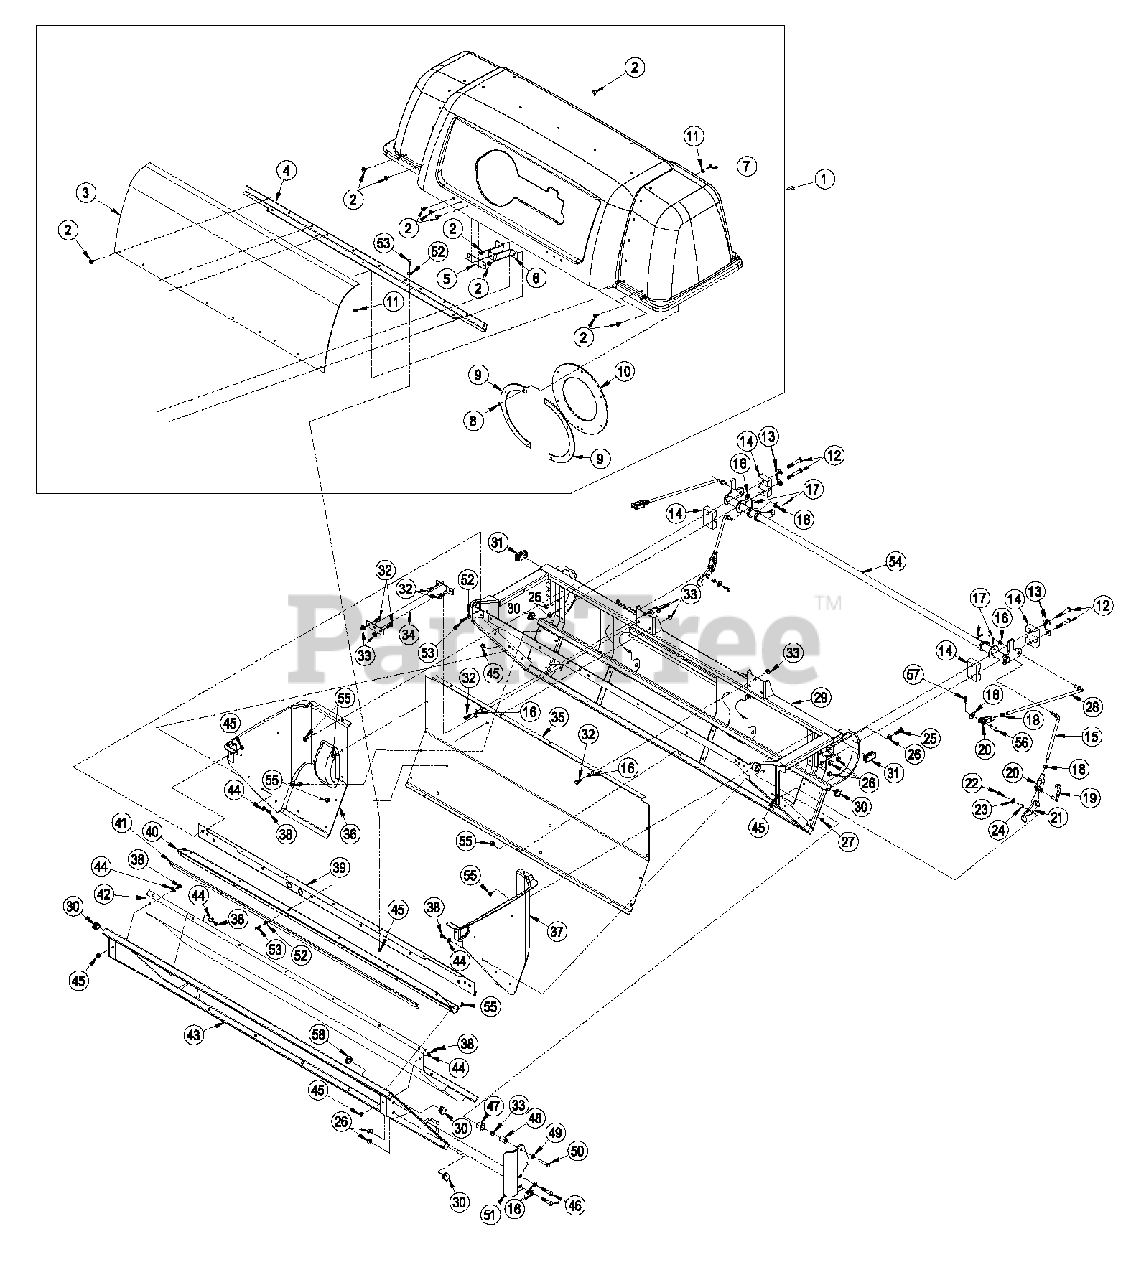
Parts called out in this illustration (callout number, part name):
1	ASM, HOOD - SERVICE ONLY
2	RIVET-BLIND
3	SCREEN-BAGGER
4	SUPPORT-SCREEN
5	PLATE-LATCH, REINFORCEMEN
6	BRACKET-MOUNT
7	SCREW-PPH
8	NUT-LOCK, NI
9	CLAMP-SEAL
10	SEAL-TUBE
11	WASHER-FLAT
12	BOLT-CARR
13	WASHER-FLAT
15	LINK-HANDLE
16	WASHER-FLAT
17	PIN-COTTER
18	NUT-HEX
19	PIN-SPRING, CLEVIS
20	YOKE-LINKAGE, BRAKE
22	SCREW-HH
23	WASHER-FLAT
25	SCREW-HH
26	NUT-HHF, WHIZ
27	NUT-LOCK, NI
28	LINK-HINGE
29	UPRIGHT-BAGGER
32	SCREW-HH
35	SHEET-WALL
36	PANEL-BAGGER, LH
37	PANEL-BAGGER, RH
38	SCREW-HH
39	REAR CROSSMEMBER ASM
40	SEAL-DOOR HINGE
41	STRAP-HOLD DOWN
42	BAG AND BOTTOM PANEL ASM
43	DOOR ASM
44	WASHER-FLAT
46	SCREW-HH
47	BUSHING
48	PIN-PIVOT, HINGE
49	WASHER-PLAIN
50	SCREW-HH
51	ARM-HINGE, LH
51	ARM-HINGE, RH
52	WASHER-FLAT
53	SCREW-HH
54	LINK-INTERMEDIATE
55	RIVET-BLIND
56	PIN-CLEVIS
57	PIN-COTTER
58	PLUG-DOME
